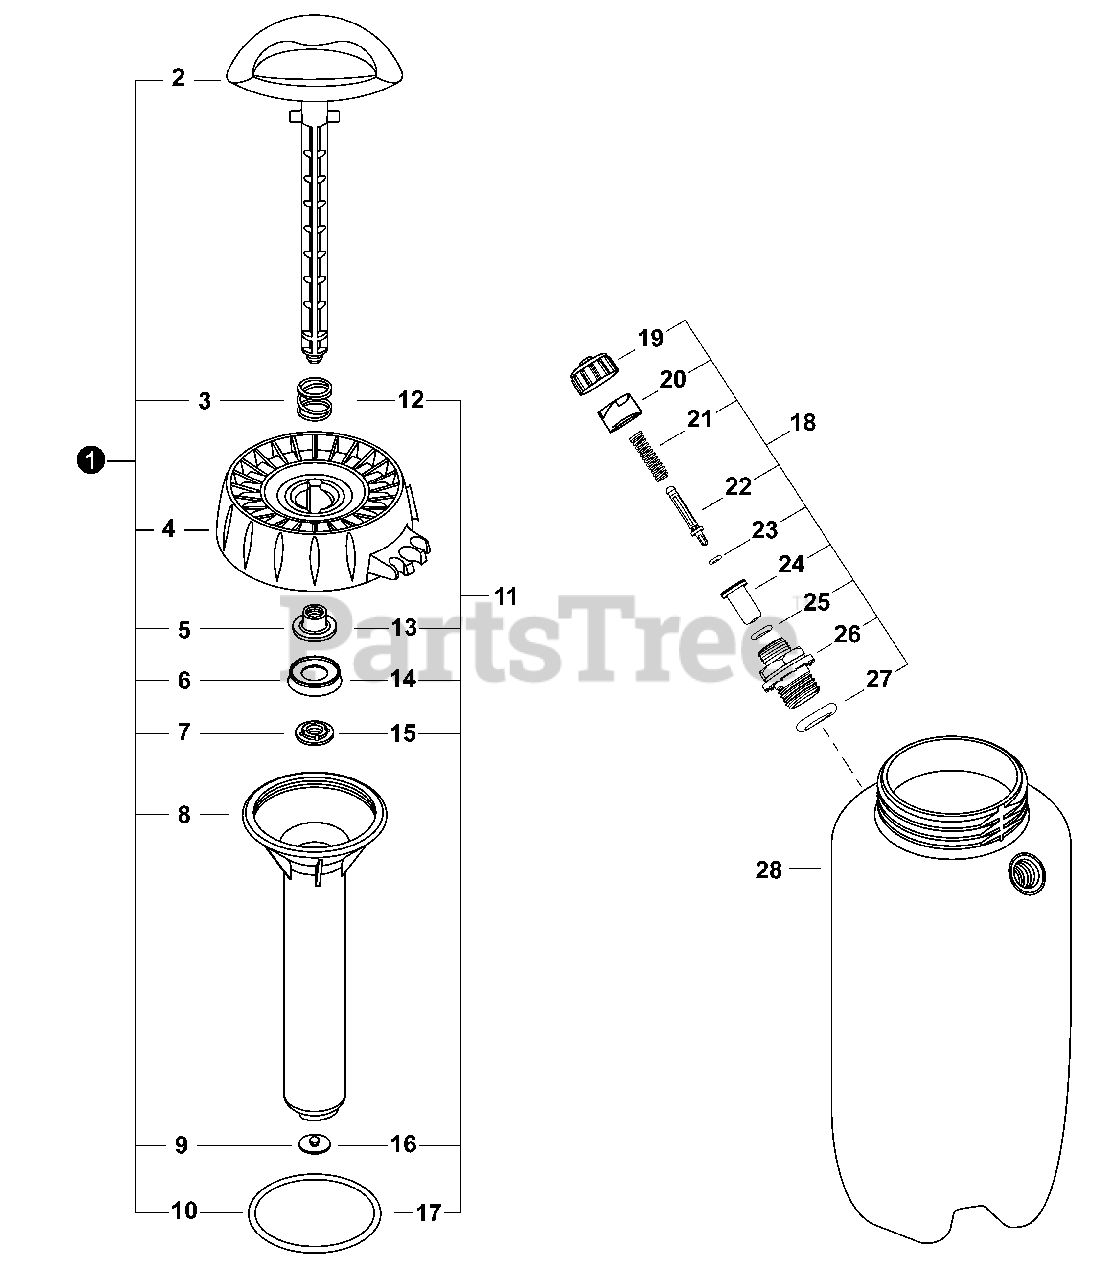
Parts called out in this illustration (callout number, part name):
1	PUMP ASSY
2	HANDLE, PUMP
3	SPRING, PUMP
4	CAP, TANK
5	ADAPTOR, PLUNGER CUP
6	CUP, PLUNGER
7	HOLDER - PLUNGER CUP
8	BARREL, PUMP
9	VALVE, CHECK
10	O-RING, CAP
11	REPAIR KIT, PUMP
12	SPRING, PUMP
13	ADAPTOR, PLUNGER CUP
14	CUP, PLUNGER
15	HOLDER - PLUNGER CUP
16	VALVE, CHECK
17	O-RING, CAP
18	VALVE, PRESSURE RELIEF
19	CAP
20	RETAINER
21	SPRING
22	PLUNGER
23	O-RING
24	BARREL, PUMP
25	O-RING
26	OUTLET, TANK 11/16
27	O-RING
28	TANK, SPRAYER
